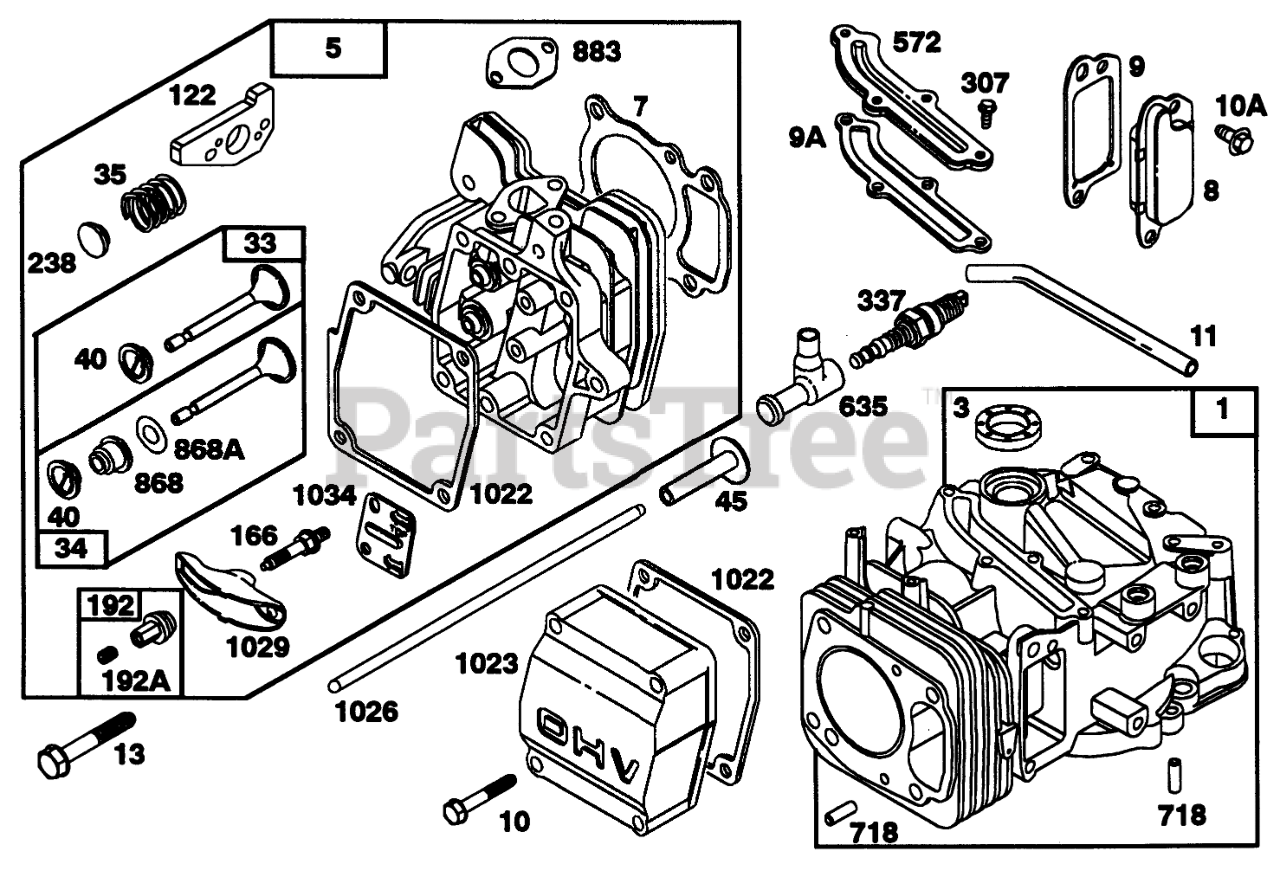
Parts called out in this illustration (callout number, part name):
1	CYLINDER ASSEMBLY
3	SEAL - OIL
5	CYLINDER HEAD
7	CYLINDER HEAD GASKET
8	Breather Assy
9	Gasket-Breather
9A	GASKET-BREATHER
10	HEX HEAD SCREW
10A	HEX HEAD SCREW
11	BREATHER TUBE
13	CYLINDER HEAD SCREW
33	EXHAUST VALVE
34	INTAKE VALVE
35	VALVE SPRING
40	SPRING RETAINER
45	VALVE TAPPET
122	ADAPTER ASSEMBLY
166	ROCKER ARM STUD
192	NUT - HEX SPECIAL
192A	Screw-Set
238	VALVE CAP
307	SCREW - SEM
337	PLUG-SPARK
572	BAFFLE - CYCLINDER
635	ELBOW-PLUG, SPARK
718	DOWEL - SLEEVE
868	SealAssy-Valve
868A	Seal-Valve
883	EXHAUST GASKET
1022	ROCKER COVER GASKET
1023	Cover-Valve
1026	PUSH ROD
1029	ROCKER ARM
1034	PUSH ROD GUIDE
